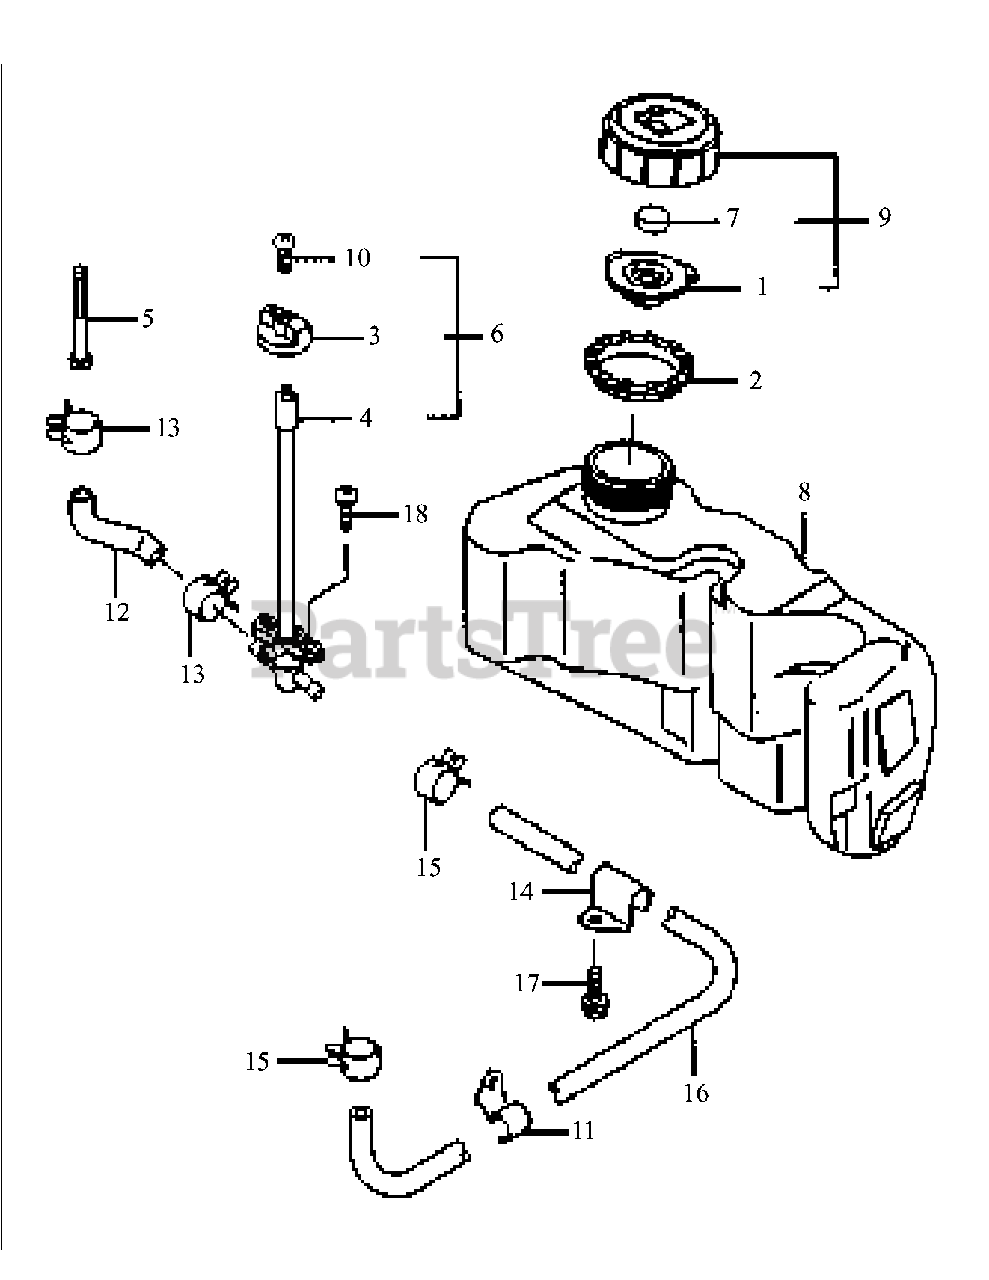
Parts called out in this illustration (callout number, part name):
1	Gasket
4	Filter Complete
6	Filter, Fuel
7	Element, Breather
13	Clamp
16	Tube 4.8x10.3x430
17	Bolt, Flange
